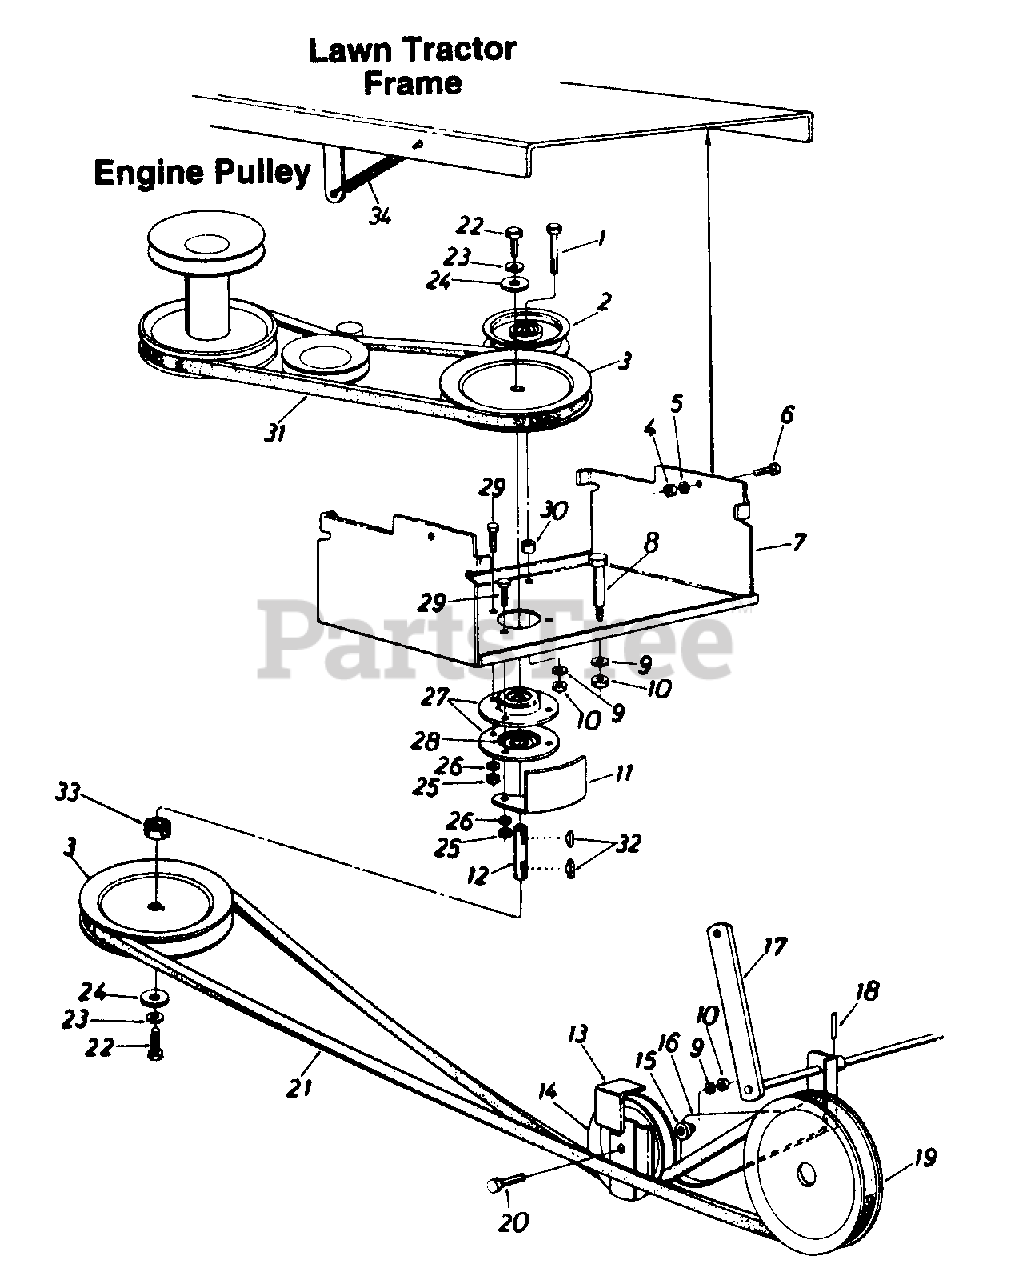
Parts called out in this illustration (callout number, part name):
1	Hex Bolt 3/8-16 x 2" Lg.
2	FL-Idler w/Flanges 3-3/4" O.D.
3	5/8" "V"-Pulley .79" I.D. x .65" O.D.
4	Hex Nut 3/8-24 Thd.
5	L-Wash. 3/8" I.D.
6	Hex Bolt 3/8-24 x .88" Lg.
7	Carriage Bracket
8	Shoulder Bolt .498" Dia.
9	L-Wash. 3/8" I.D.
10	Hex Nut 3/8-16 Thd.
11	Belt Guard
12	Shaft .787" Dia. x 3.21" Lg.
13	Belt Separator Plate
14	Fl-Idler w/Flanges 3.25"
15	Fl-Wash. .406" I.D. x 1.25"
18	Spring Pin Roll 3/16" Dia.
19	5/8" V-Pulley 1.50" I.D. x 6.5" O.D.
20	Hex Bolt 3/8-16 x 1.75" Lg.
21	V-Belt
22	Hex Bolt 5/16-18 x .88" Lg. Spec.
23	L-Wash. 5/16" I.D.
24	Fl-Wash. .344" I.D. x 1.125"
25	Hex Nut 5/16-18 Thd.
26	L-Wash. 5/16" I.D.
27	Bearing Housing 1.85" I.D.
28	Ball Bearing 1.85" O.D.
29	Hex Sems Bolt 5/16-18 x .75"
30	Spacer
32	Hi-Pro Key 3/16" x 5/8"
33	Spacer .66" I.D. x 1" O.D.
34	Extension Spring
